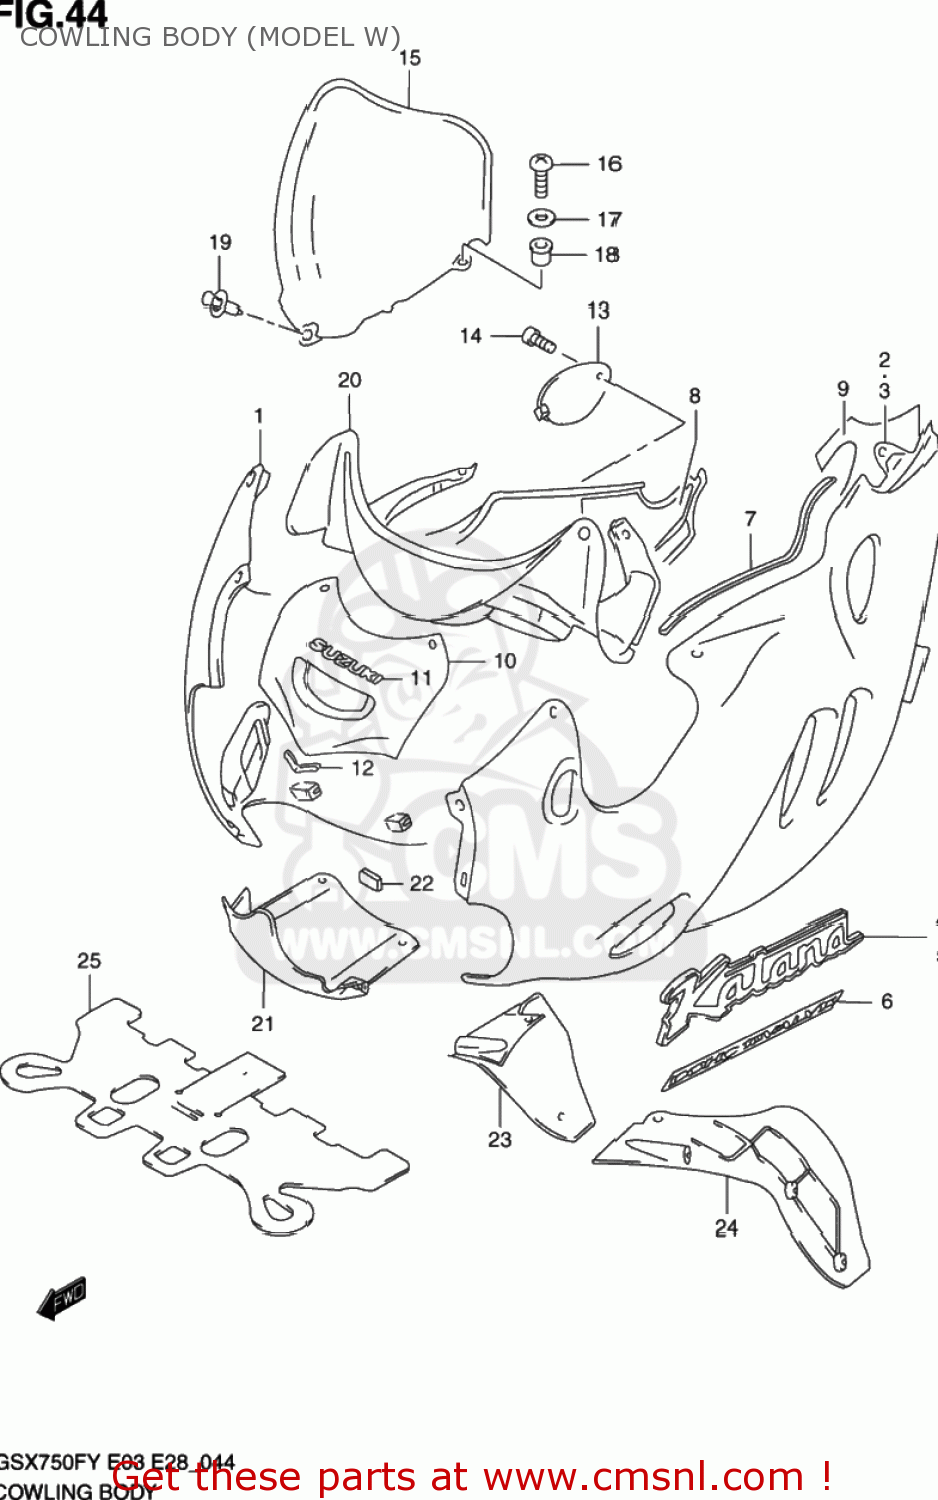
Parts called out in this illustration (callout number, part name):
1	COWLING ASSY,SIDE,R
2	COWLING ASSY,SIDE,L
3	COWLING ASSEMBLY,SIDE,LEFT
4	EMBLEM,COWLING SIDE,KATANA,R
5	EMBLEM,COWLING SIDE,KATANA,L
6	EMBLEM,COWLING SIDE
7	MOLD,COWLING
8	SHIELD,COWLING COVER,R
9	SHIELD,COWLING COVER,L
10	PANEL,COWLING CTR UPR
11	EMBLEM,SUZUKI(SILVER)
12	CUSHION,CTR PANEL UPR
13	LID,OIL
14	SCREW(6X16)
15	WINDSCREEN
16	SCREW(5X14)
17	WASHER
18	NUT
19	CLIP(BLACK)
20	PANEL,METER
21	PANEL,COWLING CTR LWR
22	CUSHION,CENTER PANEL,LOWER
23	PANEL,COWLING,INNER,RIGHT
24	PANEL,COWLING,INNER,LEFT
25	PLATE,AIR GUIDE
